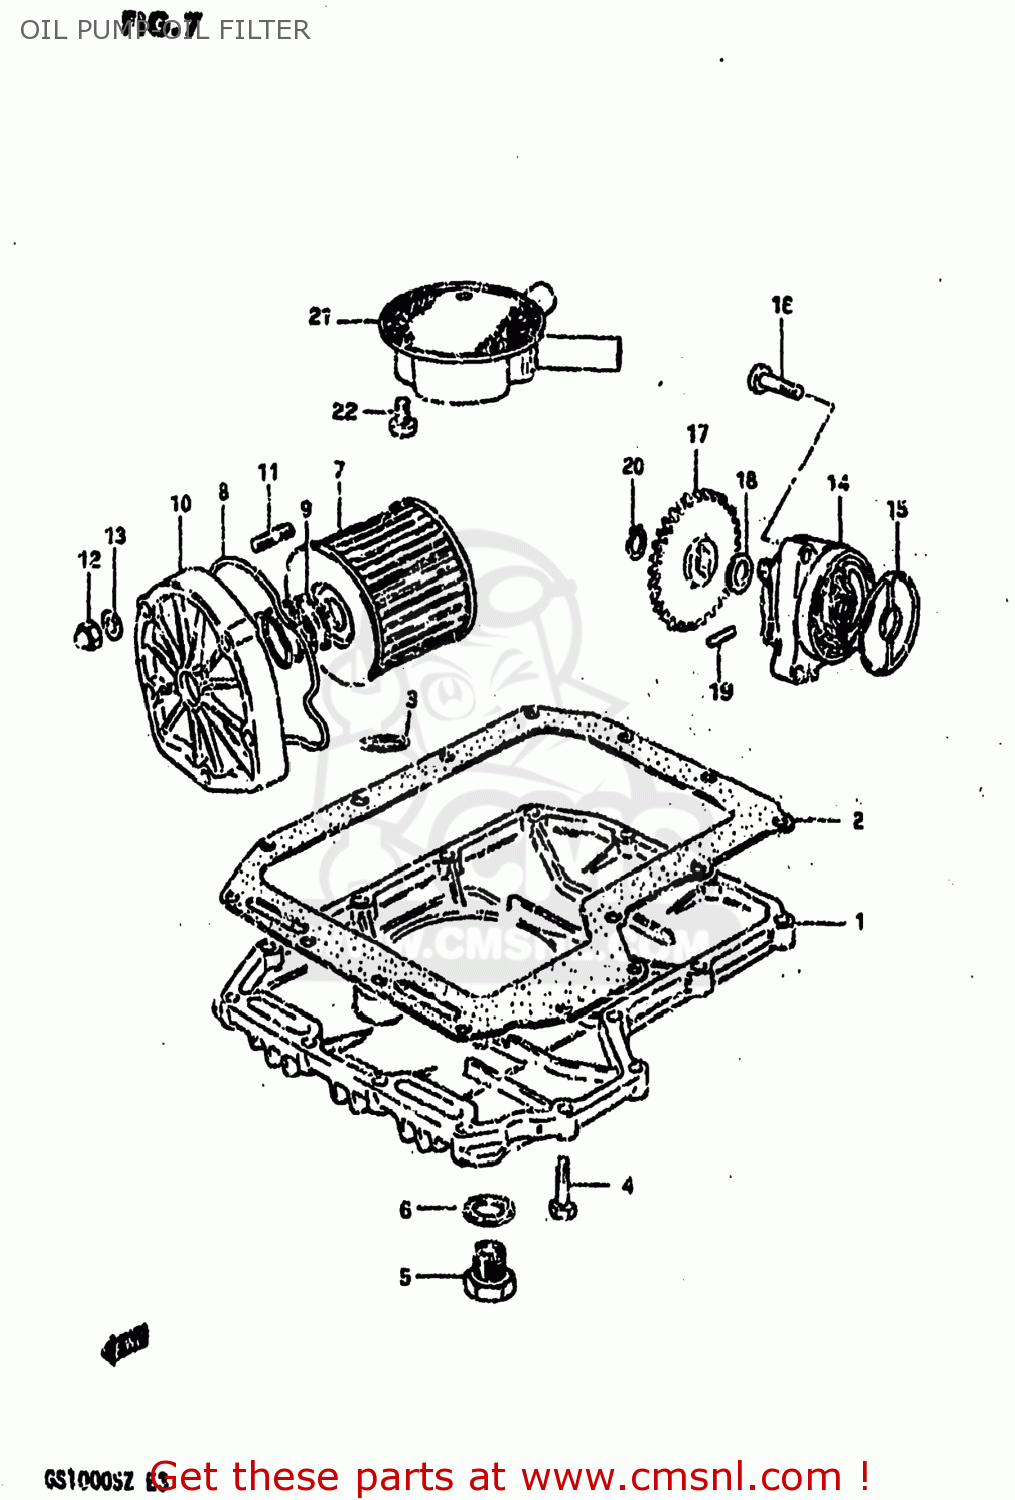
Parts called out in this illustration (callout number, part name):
1	PAN,OIL
2	GASKET,OIL PAN (MCA)
3	O RING(D:3.2,ID:12.9)
4	BOLT
5	PLUG
6	GASKET(14X19.2X2) (NAS)
7	FILTER ASSY,ENGINE OIL
8	O RING,OIL FILTER CHAMBER CAP
9	SPRING
10	CAP,ENG OIL FLTR OUTER CHAMBER
11	STUD 6X25
12	NUT
13	WASHER
14	PUMP ASSY,ENGINE OIL
15	O-RING,OIL PUMP
16	BOLT(6X32)
17	GEAR,OIL PUMP DRIVEN
18	SHIM
19	PIN(4X15.8)
20	CIRCLIP
21	STRAINER,ENGINE OIL
22	SCREW
